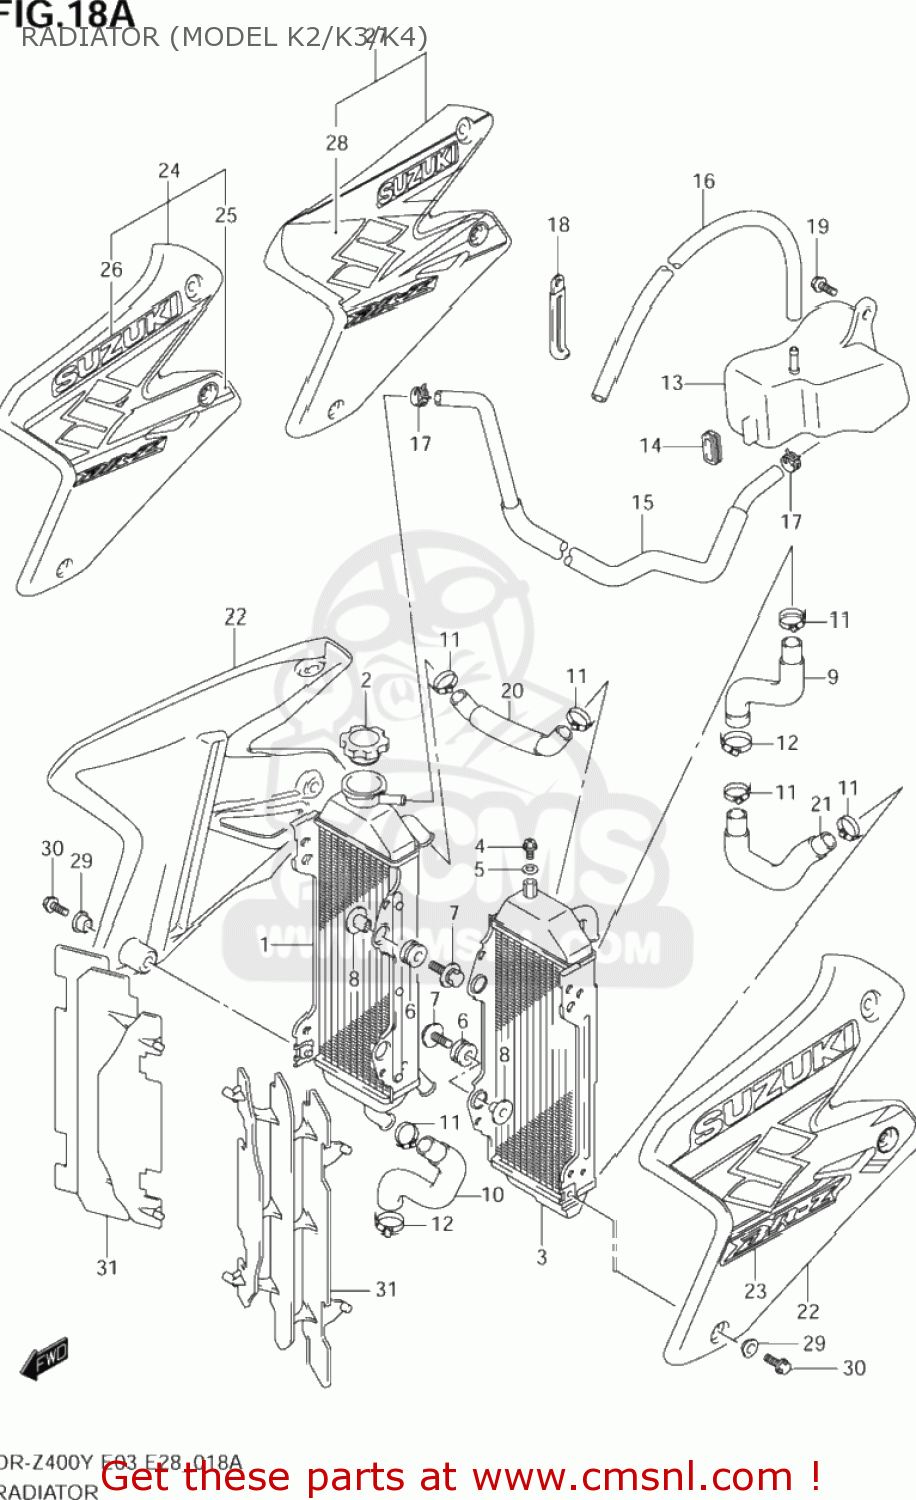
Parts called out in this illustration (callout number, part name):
1	RADIATOR,WATER,R
2	CAP,RADIATOR
3	RADIATOR,WATER,L
4	UNION BOLT,AIR VENT
5	GASKET(6.4X11.5X0.8) (NAS)
6	CUSHION,RADIATOR LWR
7	BOLT(6X25)
8	SPACER(6.5X10.5X14.1)
9	INLET HOSE
10	HOSE,RADIATOR OUTLET
11	CLAMP
12	CLAMP
13	TANK,RESERVOIR
14	CUSHION,RESERVOIR TANK
15	HOSE,RESERVOIR TANK INLET
16	HOSE(5X9X2000)
17	CLIP
18	CLAMP(L:65)
19	BOLT
20	HOSE,RADIATOR JOINT
21	HOSE,RADIATOR JOINT LWR
22	COVER,RADIATOR,R
23	TAPE SET,RADIATOR COVER,R
24	COVER,RADIATOR,R(YELLOW)
25	TAPE,RADIATOR COVER,R
26	EMBLEM,SUZUKI
27	COVER,RADIATOR,R
28	TAPE,RADIATOR COVER,R
29	WASHER
30	BOLT
31	LOUVER,RADIATOR
